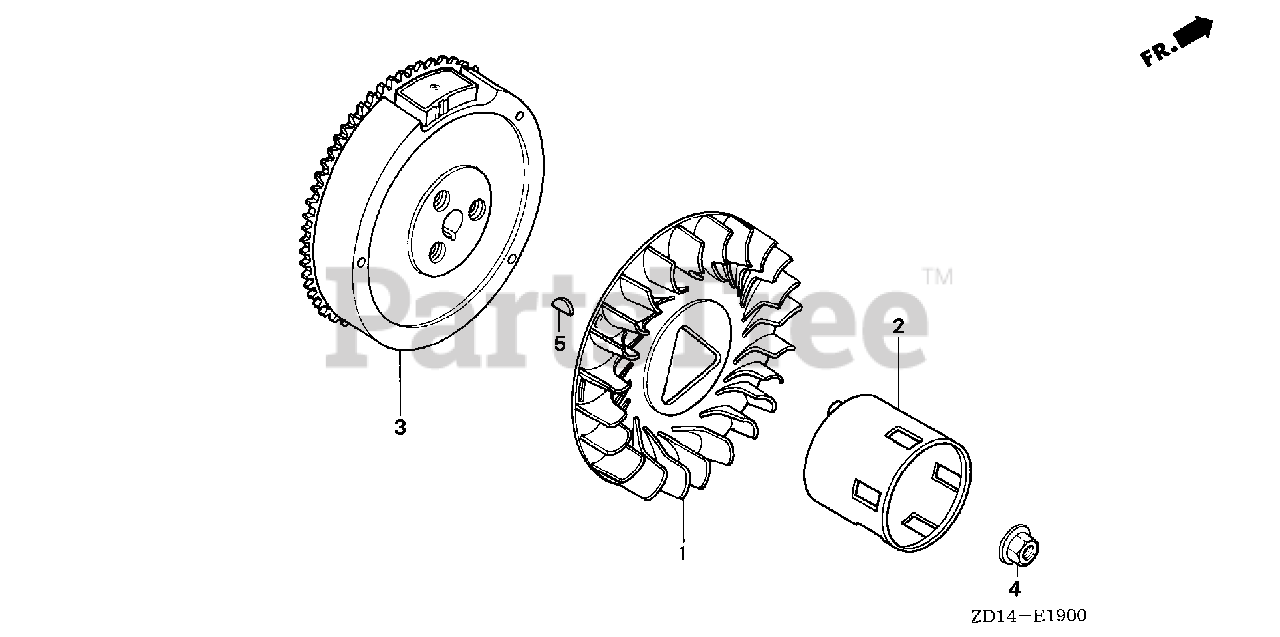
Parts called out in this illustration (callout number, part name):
1	FAN, COOLING
2	PULLEY, STARTER
3	FLYWHEEL (SEL-LAMP)
4	NUT, SPECIAL (16MM)
5	KEY, SPECIAL WOODRUFF (25X18)
